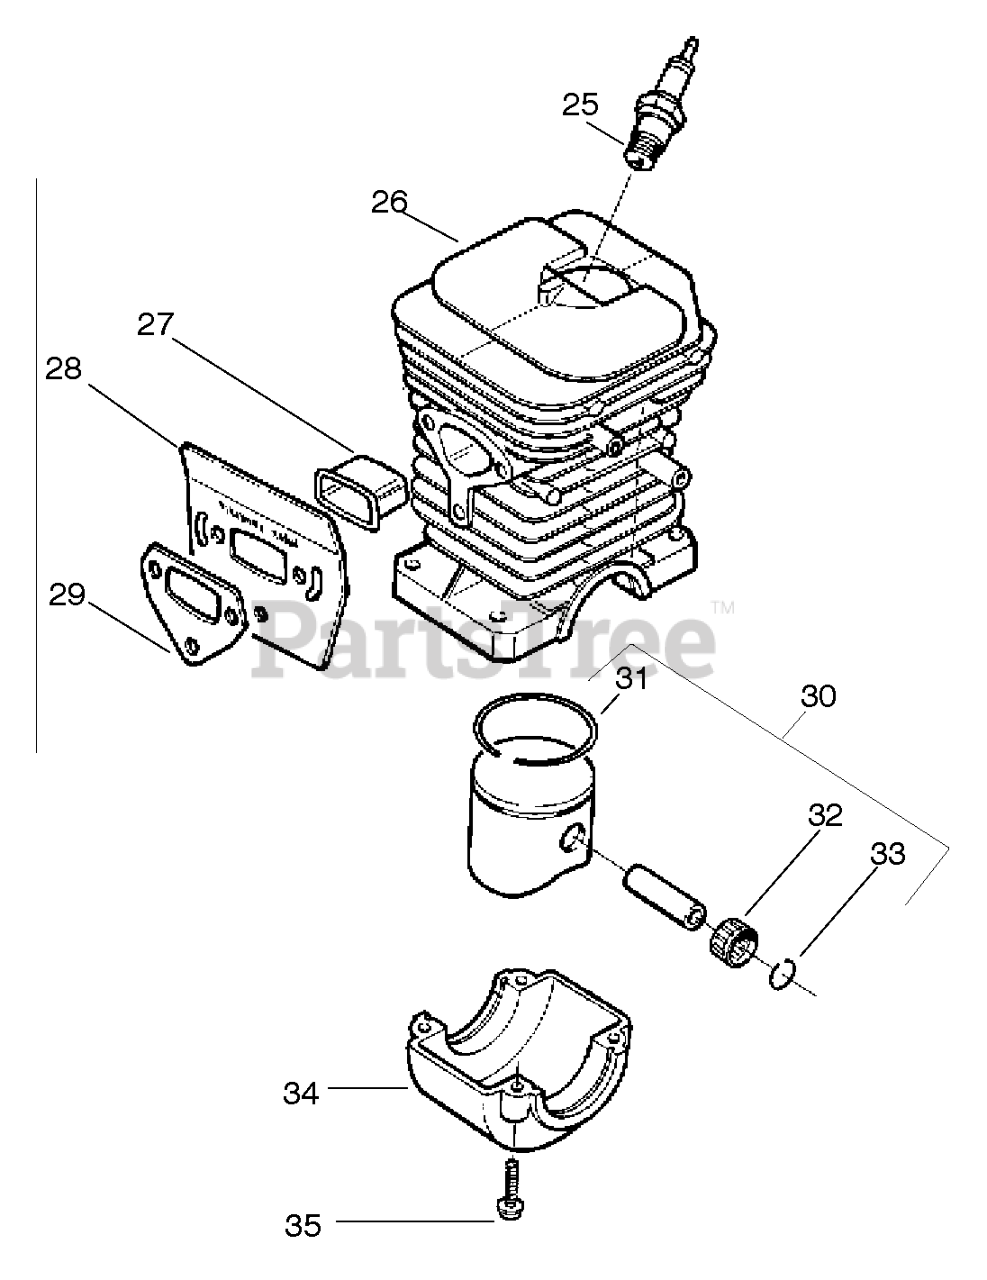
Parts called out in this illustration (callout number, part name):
25	Spark Plug (RCJ-7Y)
27	HEAT INSULATOR
28	MUFFLER PLATE
30	PISTON KIT/136
30	KIT-PISTON
31	PISTON RING 36
31	PISTON RING HV41
32	Piston Pin Bearing
33	C-CLIP,PSTN PIN 36/41
34	Cap-Crankcase
35	SCREW-M5-0.8 X 25MM(TAP)
